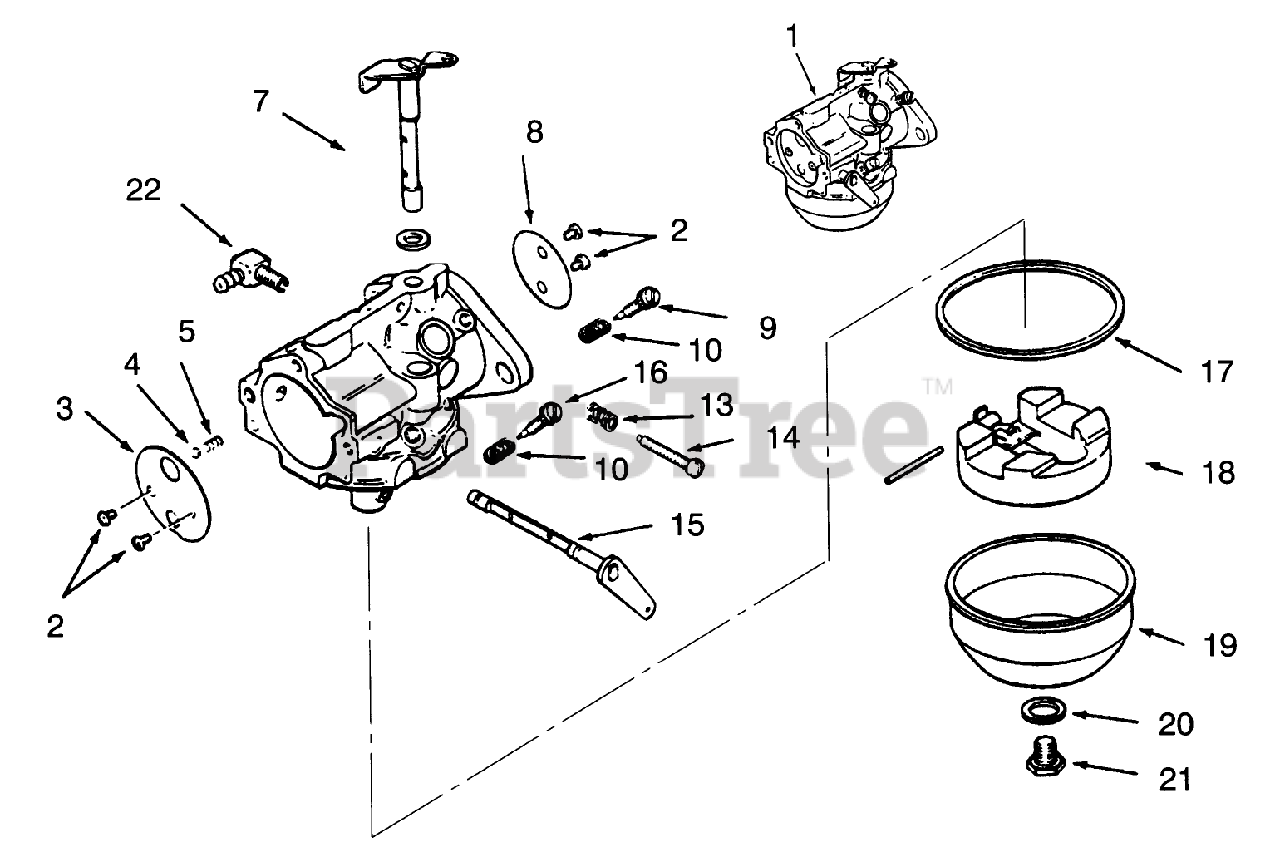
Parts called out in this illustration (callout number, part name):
1	KOHLER 47-853-20
2	KOHLER 25-086-27
3	KOHLER 47-146-08
4	KOHLER 25-194-01
5	KOHLER 25-089-03
7	KOHLER 457-144-21
8	KOHLER 25-146-02
9	KOHLER 25-368-01
10	KOHLER 25-089-02
13	KOHLER 25-089-04
14	KOHLER 25-086-26
15	KOHLER 47-090-38
16	Main-Needle
17	KOHLER 25-041-04
18	KOHLER 25-757-09
19	KOHLER 25-104-01
20	KOHLER 25-041-03
21	KOHLER 25-100-05
